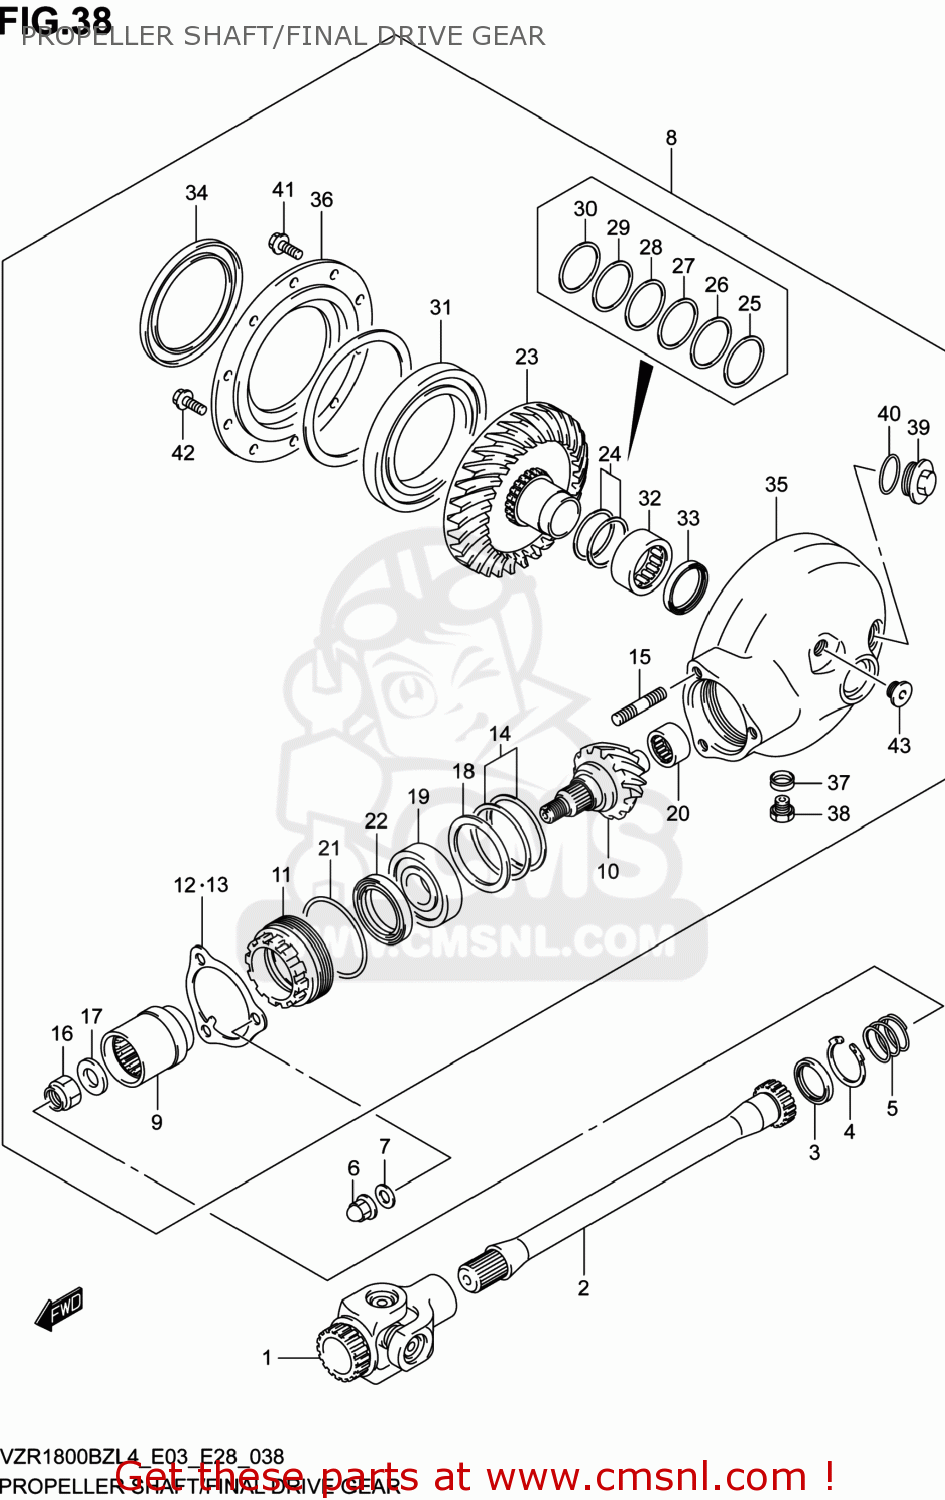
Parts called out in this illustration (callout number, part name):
1	YOKE,UNIVERSAL JOINT
2	SHAFT,PROPELLER
3	SEAL,OIL(30X40.5X5.5)
4	CIRCLIP
5	SPRING
6	NUT
7	WASHER
8	GEAR & CASE SET,FINAL BEVEL
9	COUPLING,FINAL DRIVE GEAR
10	GEAR,FINAL DRIVE BEVEL
11	STOPPER,FINAL DRIVE BEARING
12	PLATE,BEARING STOPPER
13	PLATE,BEARING STOPPER
14	SHIM SET,FINAL DRIVE GEAR
15	BOLT,STUD
16	NUT
17	WASHER(16X29X4)
18	WASHER(54X68X1.5)
19	BEARING(28X68X18)
20	BEARING(20X34X18)
21	O RING(D:3.1,ID:63.9)
22	SEAL,OIL
23	GEAR,FINAL DRIVEN BEVEL
24	SHIM SET,FINAL DRIVEN GEAR,R
25	SHIM(40X46.8X0.95)
26	SHIM(40X46.8X1.05)
27	SHIM(40X46.8X1.1)
28	SHIM(40X50X1.2)
29	SHIM(40X50X1.4)
30	SHIM(40X50X1.5)
31	BEARING(85X130X14)
32	BEARING(40X50X20)
33	SEAL,OIL(38X46X6)
34	SEAL,OIL(85X110X11)
35	CASE,FINAL GEAR
36	CASE,FINAL GEAR BEARING
37	GASKET(13.8X18.8X4.8) (NAS)
38	PLUG(MAGNETO)
39	PLUG,30X9
40	O RING(D:3.1,ID:26.4)
41	BOLT
42	BOLT
43	PLUG,16X8
